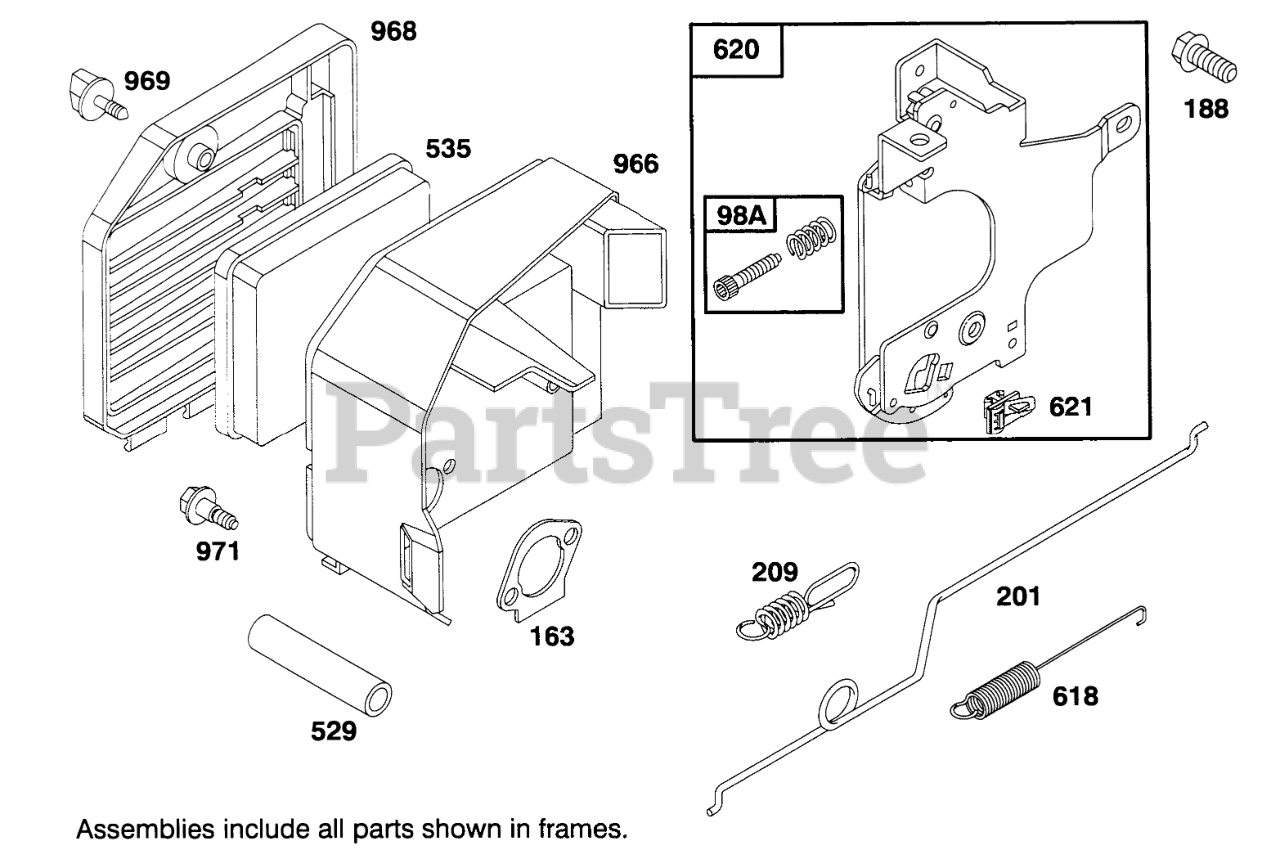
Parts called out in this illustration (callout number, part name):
98A	SPEED ADJUST. SCREW ASM
163	AIR CLEANER GASKET
188	Screw-Cap
201	GOVERNOR LINK
209	GOVERNOR SPRING
529	TUBE - BREATHER
535	FILTER ELEMENT
618	RETURN SPRING
620	CARBURETOR BRACKET
621	STOP SWITCH
966	AIR CLEANER BASE
968	AIR CLEANER COVER
969	AIR CLEANER SCREW
971	AIR CLEANER SCREW
